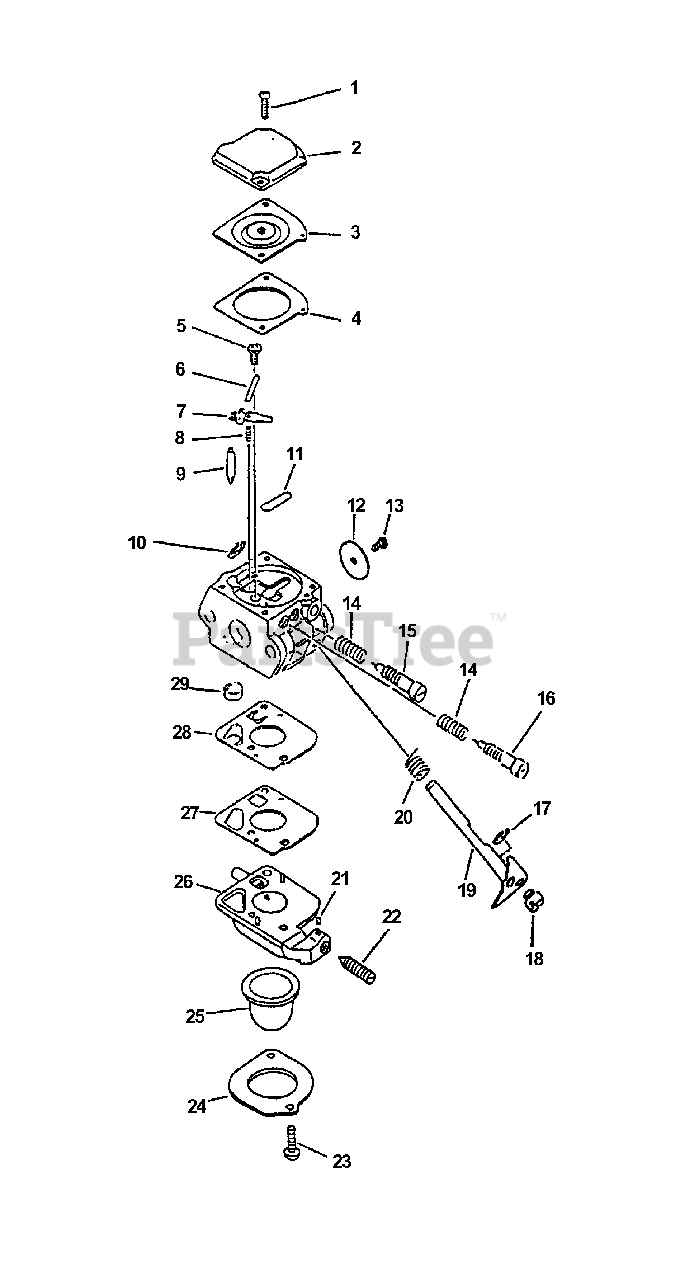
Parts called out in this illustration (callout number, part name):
2	COVER, DIAPHRAGM
3	DIAPHRAGM, METERING
4	GASKET, METERING
5	SCREW, METERING LEVER PIN
6	PIN, METERING LEVER
7	LEVER, METERING
8	SPRING, METERING LEVER
9	VALVE, INLET NEEDLE
11	PLUG, WELCH
12	VALVE, THROTTLE
14	SPRING, NEEDLE
15	NEEDLE, LOW SPEED
16	NEEDLE, HIGH SPEED
19	SHAFT, THROTTLE
20	SPRING, THROTTLE RETURN
21	PIECE, FRICTION
22	SCREW, IDLE ADJUST
24	RETAINER
25	BULB, PURGE
26	BODY ASSY, PURGE
29	STRAINER
